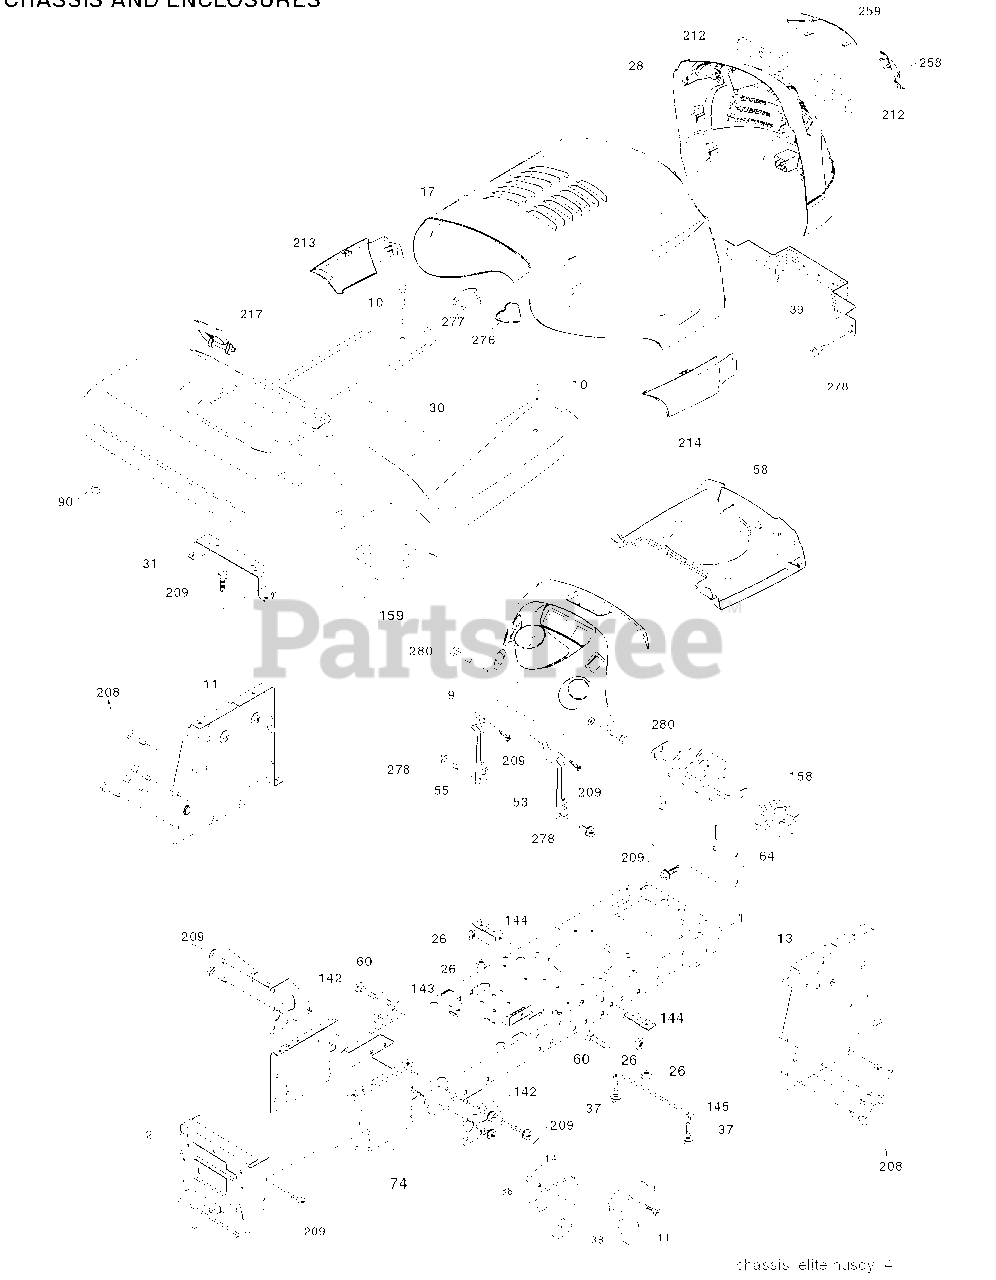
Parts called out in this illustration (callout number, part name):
1	Chassis Stamping
9	Dash P/L M
10	Bolt Carriage 3/8-16 x 1
11	Panel Dash Lh
13	Panel Dash Rh
14	Screw Thdrol 3/8-16 x 1/2
17	Hood
26	Nut Lock Hex W/Ins 3/8-16 unc
28	Grille/Lens Asm.
30	Fender Footrest STLT Pnt
31	Bracket Support Fender
37	Screw Thdrol 5/16-18 x 1/2 TYT
38	Bracket Asm Pivot Mower Rear
39	Bracket Pivot
53	Bracket Dash RH
55	Bracket Dash LH
58	Air Duct Engine
60	Bolt Rdhd Sqnk 3/8-16 unc x 3/4
64	Dash Lower STLT
74	Nut Crownlock 3/8-16 unc
90	Nut Self-thd Wsh-Hd 1/4
142	Plate Reinforcement STLT
143	Bracket Swaybar Chassis
144	Bracket Pnt Footrest STLT
145	Rod Pivot Chassis/Hood
158	Bracket Parking Brake
159	Cupholder
208	Screw Thdrol 3/8-16 x 1/2 TYT Bl
209	Screw 3/8-16 x 3/4
212	Insert Lens Reflect
213	Skirt Side LH
214	Skirt Side RH
217	Console Fuel Window
258	Lens RH
259	Lens LH
276	Bumper Hood RH
277	Bumper Hood LH
278	Screw 10 x 3/4 Single Lead Hex
280	Screw 3/18-16 x 1
